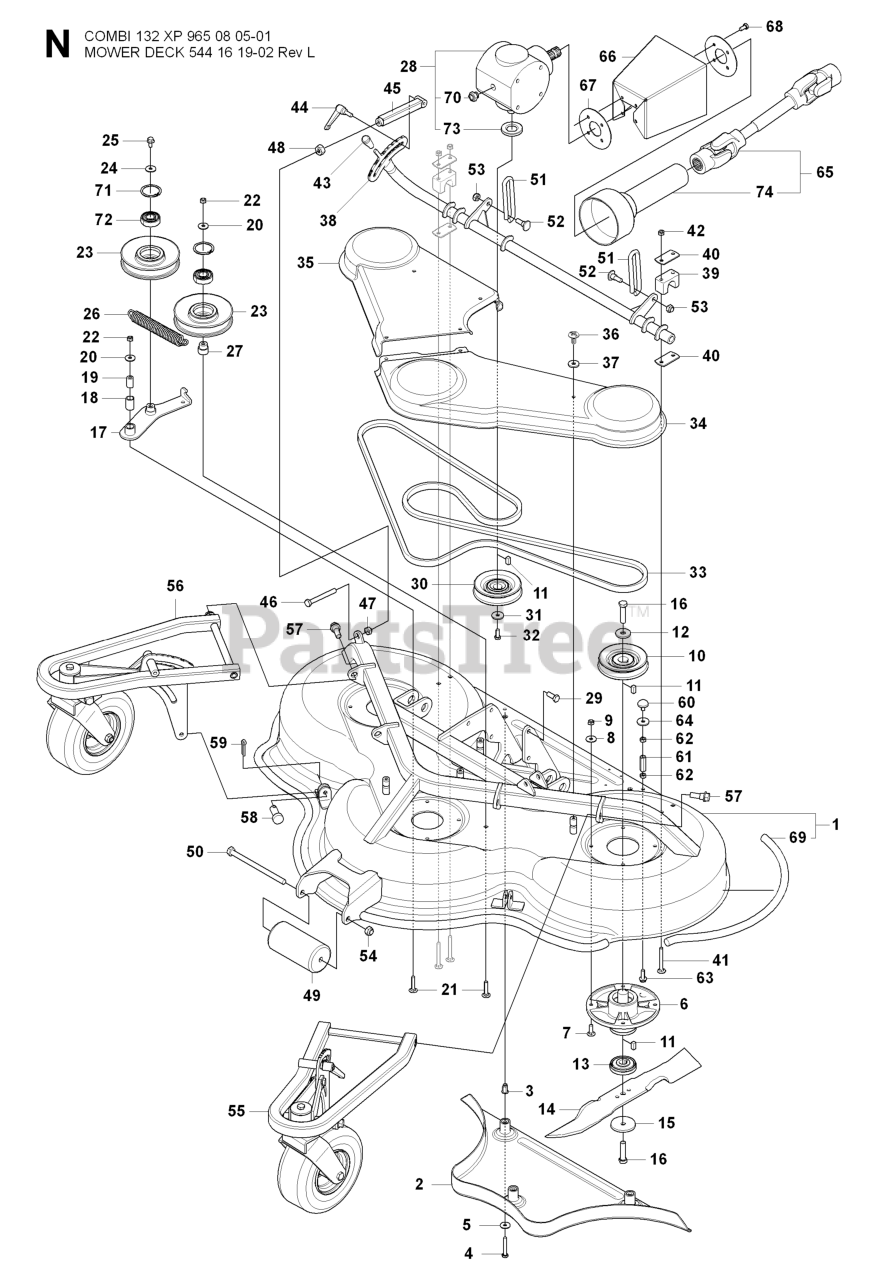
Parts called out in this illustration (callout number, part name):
1	CUTTING DECK ASSY C132
3	BLIND RIVET NUT
5	WASHER BRB 8.4X17
8	WASHER BRB 8.4X17
9	LOCKNUT M8
10	PULLEY SPB DP112 COMPLETE
14	BLADE REAR DISCHARGE/MULCH C13
17	BELT TENSIONER CUTTING DECK
21	Screw Mvbf 8 X 40
22	LOCKNUT M8
25	BOLT FLANGE - M8X16
26	DRAW SPRING L=122
28	BEVEL GEAR
29	Screw M10x25
30	PULLEY SPB DP112
32	SCREW 8X20
35	BELT COVER C132 R
39	BEARING COVER
42	LOCKNUT M8
44	TURNING KNOB M 8
45	PARALLEL ROD C 132
48	NUT
49	ROLLER
52	SCREW LINK
53	NUT
55	WHEEL SUSPENSION LEFT
56	WHEEL SUSPENSION RIGHT
60	ANTIVIBRATION ELEMENT
62	NUT
68	REPL BY 725 24 49-51
71	CIRCLIP SGH 47
72	BALL-BEARING 6204-2RS
